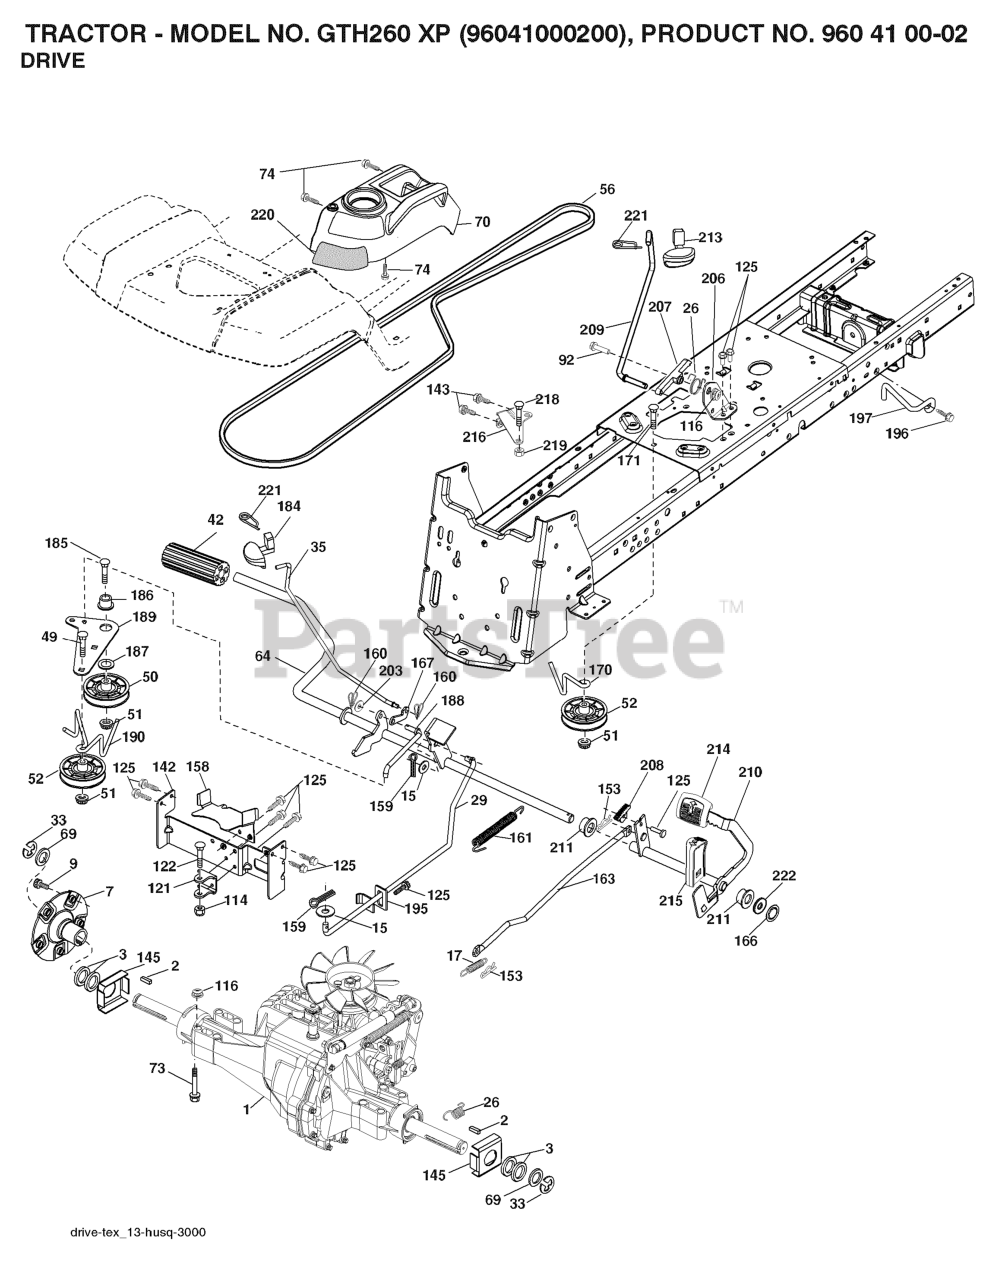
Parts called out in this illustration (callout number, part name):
2	KEY 1/4 X 2.5
7	HUB.ASM.WHEEL.REAR.23"TEX
15	WASHER
17	SPRING.BRAKE.HG3000/3500
26	SPRING.RETURN.CRUISE
29	ROD.BRAKE.HG3000/3500
33	E RING HYT
35	ROD.BRAKE.PARKING.GT.H
42	COVER, PEDAL (1 2)
50	IDLER.FLAT.910.OFFSET
51	NUT LOCK FLG 3/8-16 UNC
52	IDLER.V-GROOVE.910.OFFSET
56	BELT.V.GROUND.DRIVE
64	SHAFT.ASM.PEDAL.BRK.CNTR
70	RP CONSOLE.ASM.PCH.W/TB
73	BOLT HEX FLGHD 5/16-18X3 GR. 5
74	SCREW.HI-LO.CONSOLE
92	BOLT
114	NUT.71038.31-18.HEX.NYLOCK
116	NUT LOCK HEX FLANGE 5/16-18
121	BRACKET STRAP TORQUE
122	BOLT.5/16-18X2.5
125	SCREW
142	STRAP.TORQUE.HG300/3500
143	Screw 5/16-18 x 1/2 Hex, Self Tapping 5/16-18 x 1/2
145	WASHER.AXLE.FLANGE.HG-3000
148	SCREW, 3/8-16X3/4
153	RETAINER M
158	KEEPER BELT
159	COTTER PIN
160	RETAINER CLIP
161	SPRING.RETURN.CLUTCH.2006
166	NUT.PUSH.625.2006
167	LATCH.BRAKE.SPRING
170	KEEPER.V-IDLER.CENTER.
184	HANDLE.PARKG.BRK.HUSQ X667
186	SPACER.RETAINER
187	WASHER 12/32X2X10GA
188	RP.LINK.CLUTCH.GROUND.DRIVE
189	BELLCRANK.GROUND.DRIVE.TEX.
190	KEEPER.BELLCRANK.DRIVE
196	SCREW 3/8-16X1
197	BRKT.ANIT-ROTATION.CLUTCH
203	WASHER
206	BRKT.MOUNT.LATCH.CRUIS
207	LATCH.CONTROL.CRUISE
208	GEAR.SECTOR.CONTROL.CR
209	ROD.CONTROL.CRUISE.GT.
210	ROCKER.ASM.PEDAL.CONTR
211	BEARING.NYLON
213	KNOB.CONTROL.CRUSIE.HU
214	PEDAL.FORWARD.TEX.GT.4
215	PEDAL.REVERSE.TEX.GT.4
216	BRACKET.PULLEY.IDLER.W/TEX
218	BOLT.5/16-18X1-1/4 FULL.THREAD
219	SPACER.FENDER
220	REFLECTOR.RH.TEX GT
221	RETAINER.SPRING.CLIP.H
222	WASHER
223	BOLT
